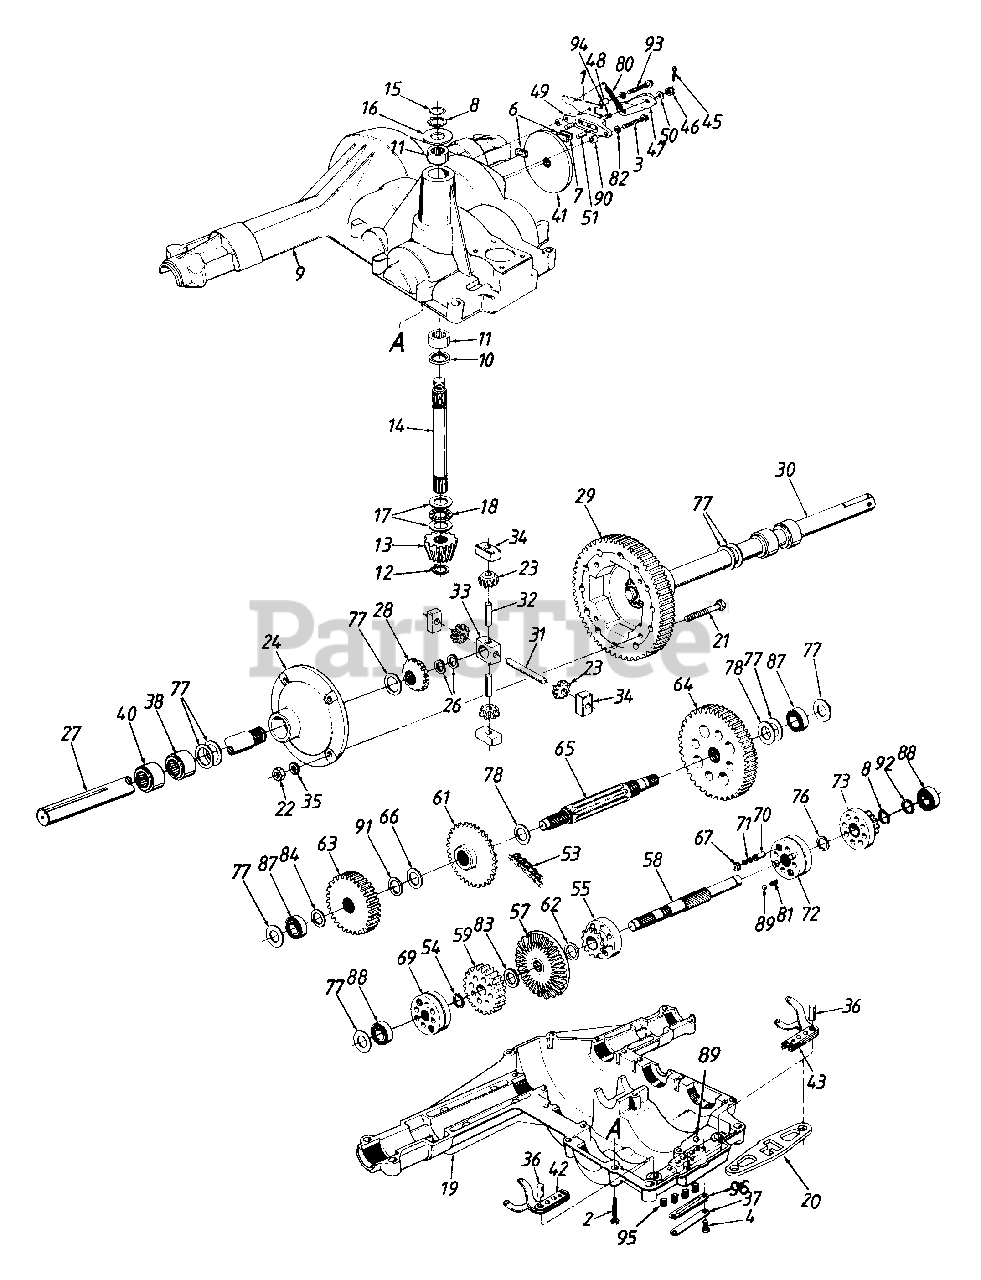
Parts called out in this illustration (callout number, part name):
1	Brake Return Bracket
2	Hex Bolt 1/4-20 x 1.25" Lg.
3	Hex Bolt 1/4-20 x 1.5" Lg. (Gr. 5)
4	Hex Wash. Tap Scr. 1/4-20 x .5" Lg.
6	Brake Puck
7	Puck Plate
8	Retainer Ring
9	Upper Housing
10	Oil Seal
11	Needle Brg. 5/8" I.D. x 7/8" O.D.
12	Snap Ring
13	Input Pinion 15T
14	Input Shaft
15	Wire Ring
16	Thrust Washer 5/8" I.D.
17	Thrust Washer
18	Thrust Bearing
19	Lower Housing
20	Lockout Plate
21	Hex Bolt 3/8-24 x 2.0" Lg.
22	Hex L-Nut 3/8-24 Thd. (Gr. 5)
23	Differential Gear 10T
24	Differential Housing Cover Ass'y.
26	Retainer Ring
27	Axle R.H.
28	Differential Gear 14T
29	Differential Bull Gear 60T
30	Axle L.H.
31	Cross Shaft
32	Cross Shaft - Special
33	Differential Pinion Block
34	Differential Thrust Block
35	Spr. Wash. .39" I.D. x .62" O.D.
36	Shift Pin
37	Spring Plate
38	Axle Bearing Ass'y.
40	Axle Bearing Ass'y.
41	Brake Disc
42	Shift Arm Ass'y. - R.H.
43	Shift Arm Ass'y. - L.H.
45	Cotter Pin 3/32" Dia.
46	Castle Nut 5/16-24 Thd.
47	Brake Actuating Arm
48	Sq. Hd. Bolt 5/16-24 Thd.
49	Brake Yoke
50	Fl-Wash. 11/32" I.D. x 7/8" O.D.
51	Brake Actuating Pin
53	#420 Chain 1/2 Pitch x 28 Links
54	Retainer Ring
55	Reverse Sprocket Ass'y.
57	Bevel Gear 47T
58	Drive Shaft
59	Spur Gear Ass'y.
61	Sprocket 22T
62	Fl-Wash. .81" I.D. x 1.18" O.D.
63	Spur Gear 31T
64	Spur Gear 45T
65	Output Shaft 9T
66	Spacer
67	Shift Spring Plug
69	Forward Shift Collar
70	Drive Pin
71	Drive Spring
72	Creeper Shift Collar
73	Creeper Collar Plate Ass'y.
76	Fl-Wash. .65" I.D. x .97" O.D.
77	Fl-Wash. 1" I.D. x 1.56" O.D. x .010" Thk.
78	Fl-Wash. 1.0" I.D. x 1.56" O.D.
80	Ext. Spring 1.14" Lg.
81	Detent Spring
82	L-Wash. 1/4" I.D.
83	Fl-Wash. 5/8" I.D. x 1.0" O.D.
84	Fl-Wash. .68" x 1.12"
87	Ball Brg. .669" I.D.
88	Ball Bearing
89	Ball Detent .25" Dia.
90	Spacer .254" I.D. x .5" 0 D.
91	Fl-Wash. .69" I.D. x 1.06" O.D.
92	Fl-Wash. 5/8" I.D. x 1.0" O.D. x .020" Thk.
93	Hex Wash Hd. Patch Bolt 1/4-20 x 2-1/4" Lg.
94	Spacer .256" I.D. x .75" 0.D.
95	Detent Spring
96	Spring Plate Shim
